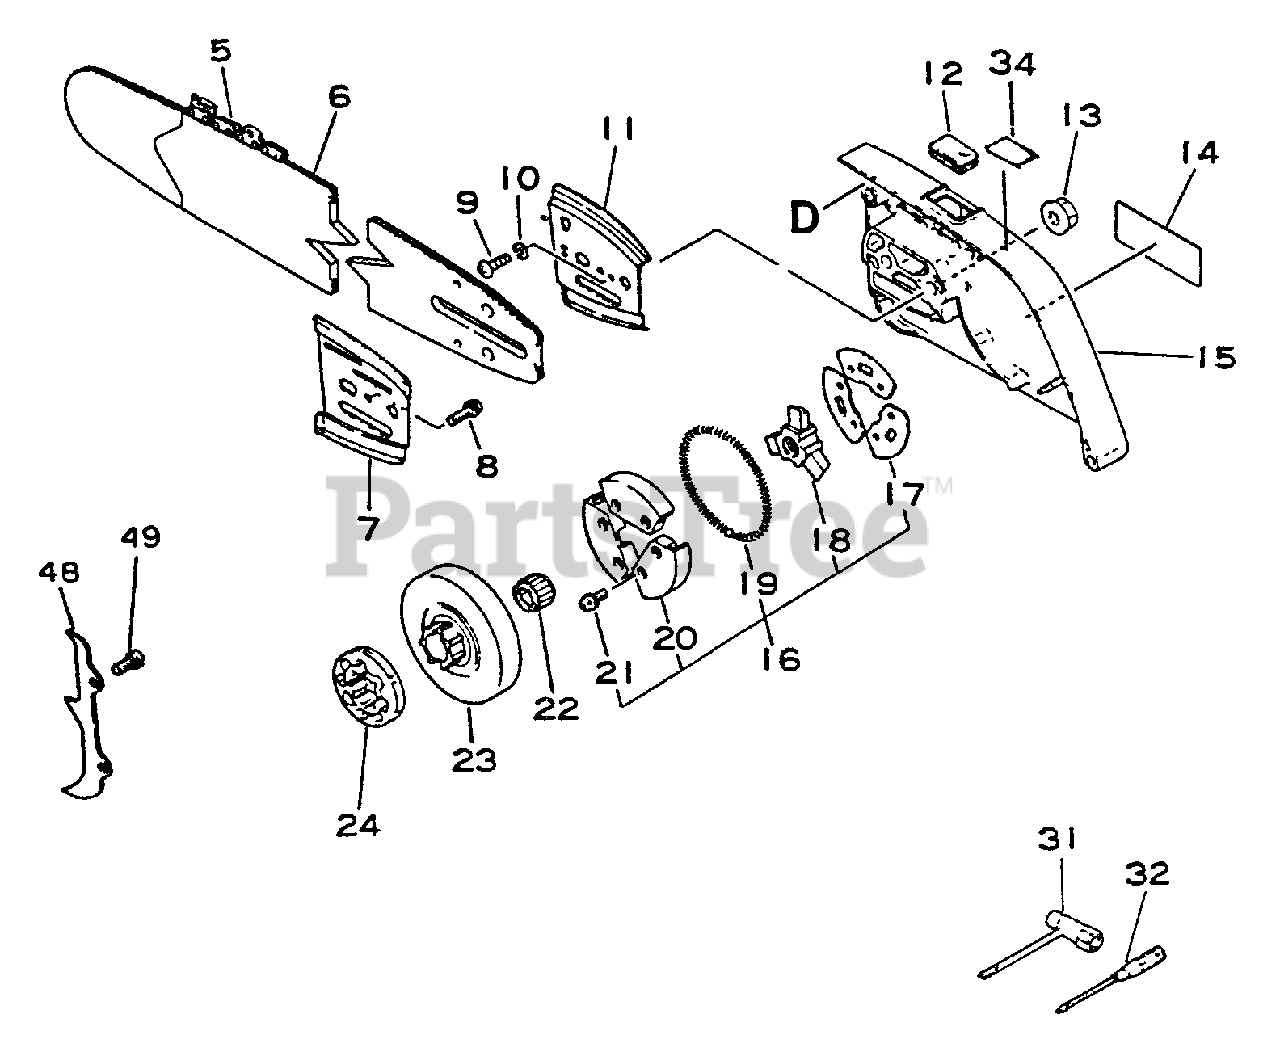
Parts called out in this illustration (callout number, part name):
5	CHAIN, SAW
6	GUIDE BAR
7	PLATE, GUIDE - INNER
8	SCREW - 4X8
9	SCREW - 3X6
10	LOCKWASHER - 3
11	PLATE, GUIDE - OUTER
13	NUT - FLANGE
14	LABEL - ECHO
15	GUARD, SPROCKET
16	CLUTCH ASSY
17	PLATE, CLUTCH
18	HUB, CLUTCH
19	SPRING, CLUTCH
20	CLUTCH SHOE SET
21	SCREW - 4X8
22	BEARING, NEEDLE
23	DRUM, CLUTCH
24	SPROCKET, RIM
25	LABEL - CAUTION
31	T-WRENCH - 13X19mm
32	SCREWDRIVER
48	SPIKE KIT
